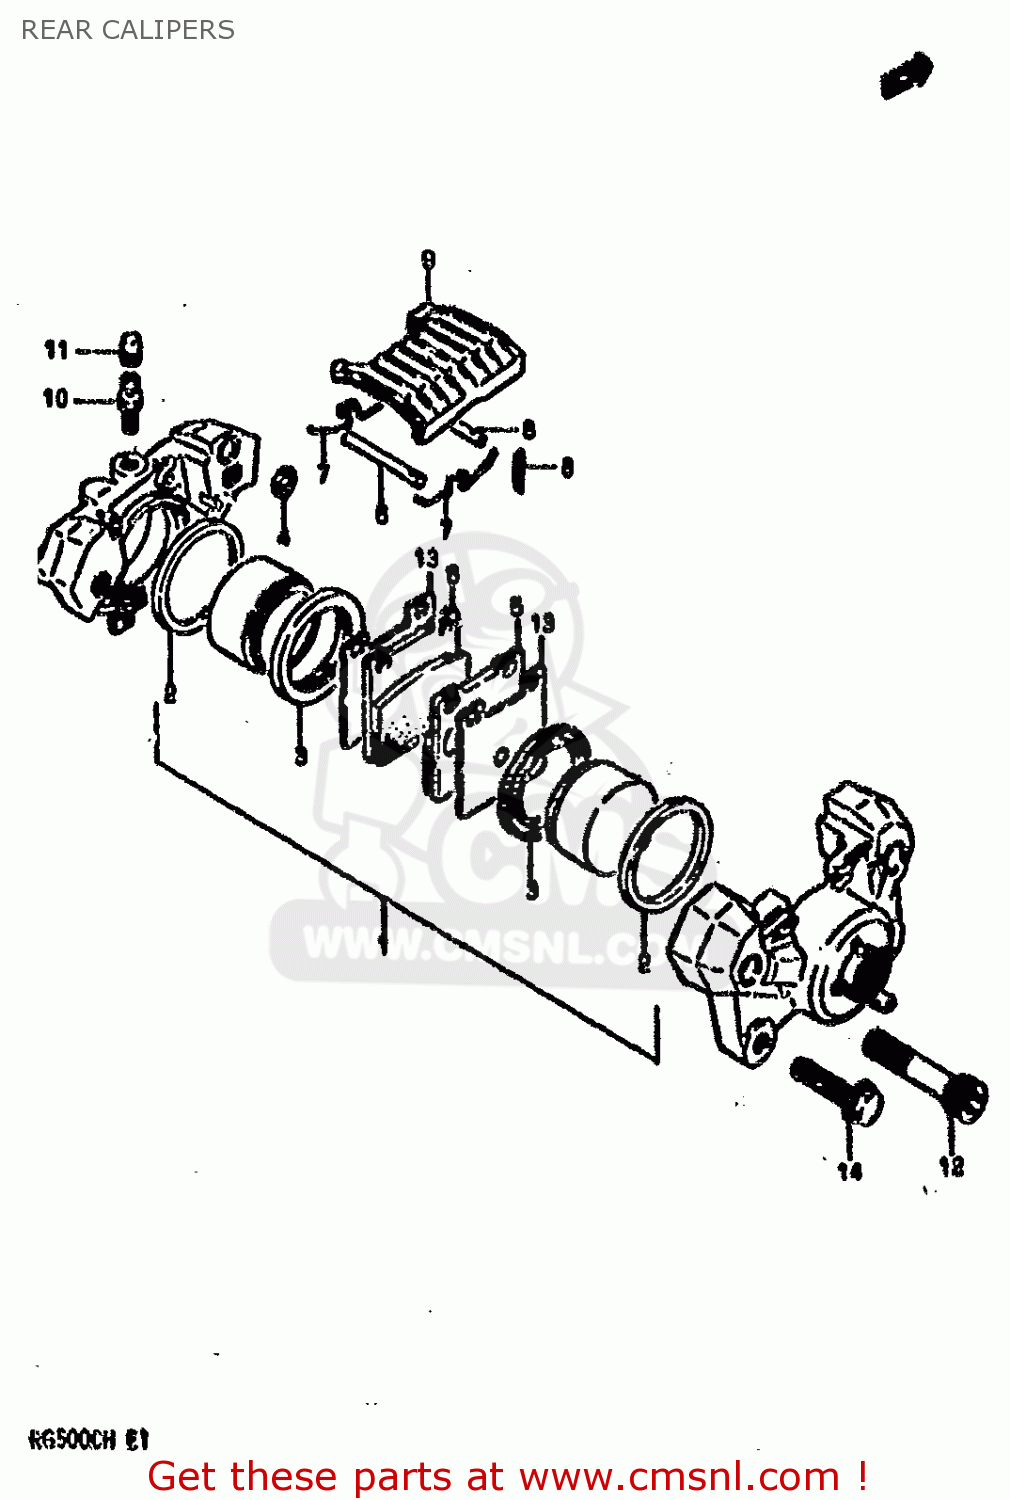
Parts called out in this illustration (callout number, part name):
1	PISTON SET
2	SEAL,PISTON
3	BOOT
4	SEAL,JOINT
5	ASBESTOS !!!
6	PIN,PAD
7	SPRING
8	CLIP,PAD PIN
9	COVER
10	BLEEDER
11	CAP,BREATHER
12	BOLT
13	SHIM,PAD
14	BOLT
